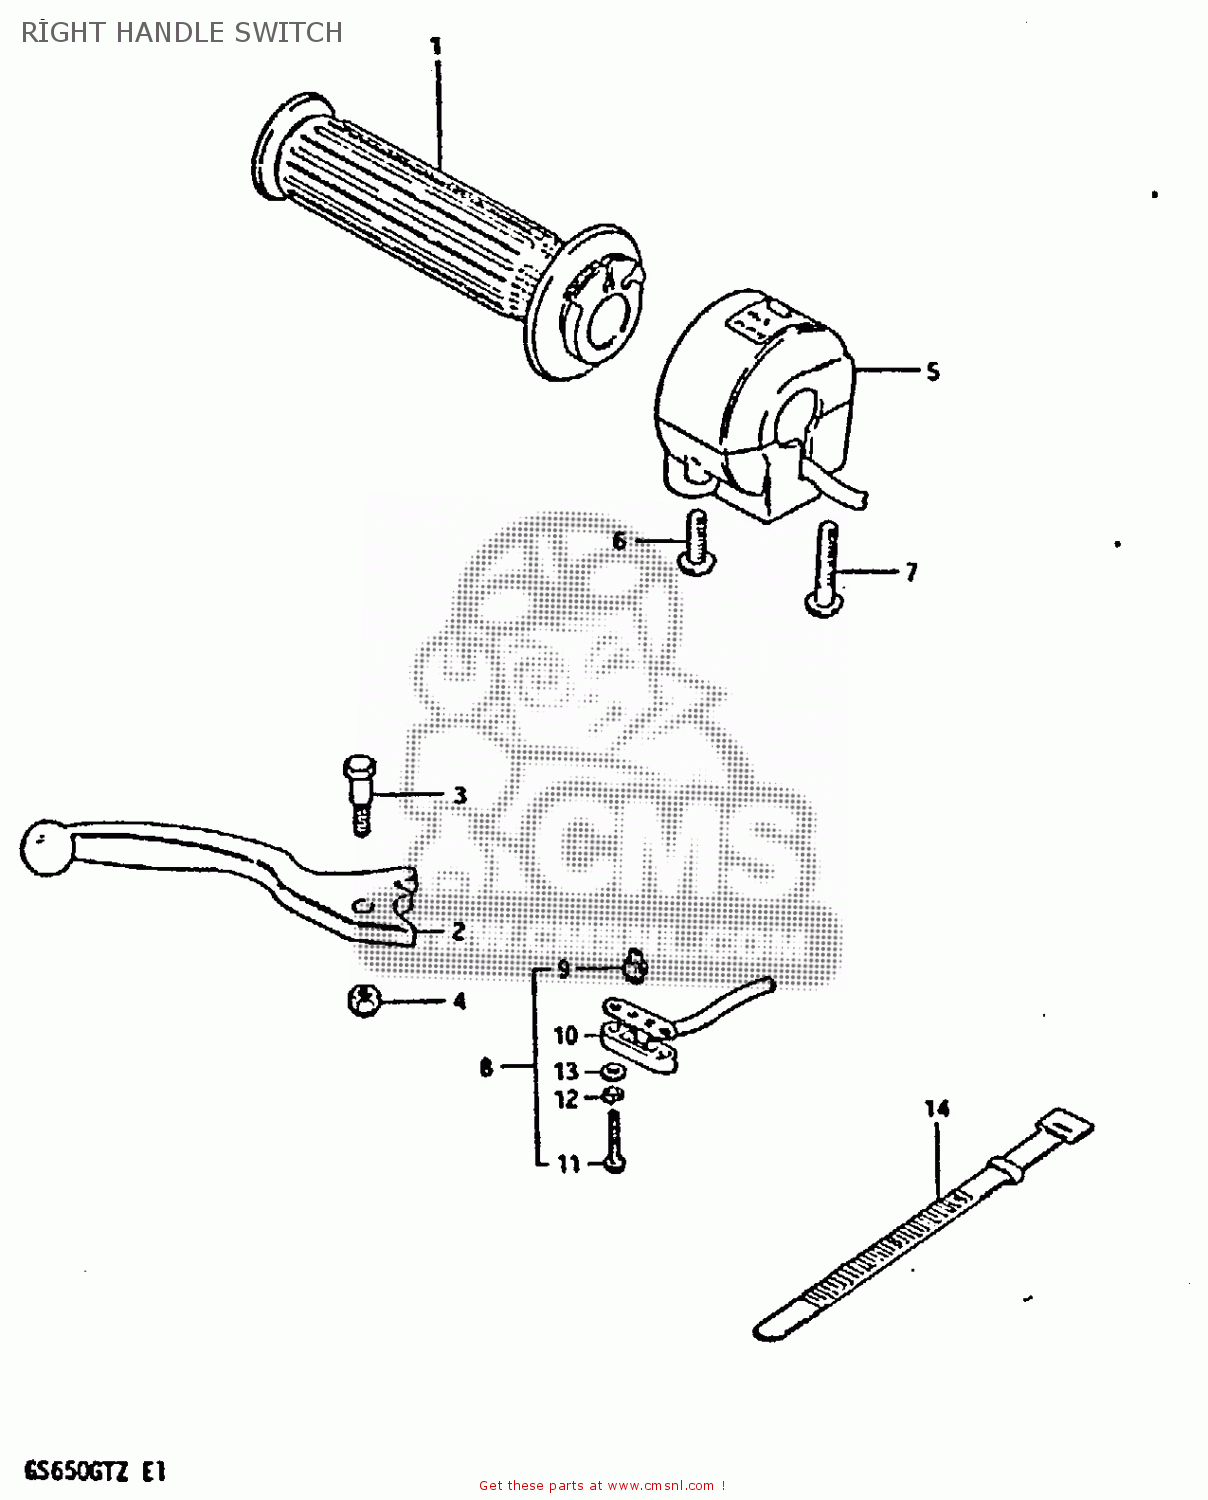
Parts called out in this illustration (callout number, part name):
1	GRIP,THROTTLE
2	LEVER,BRAKE
3	BOLT
4	NUT 6MM
5	SWITCH ASSY, HANDLE RH
6	SCREW
7	SCREW
14	CLAMP(L:120)
